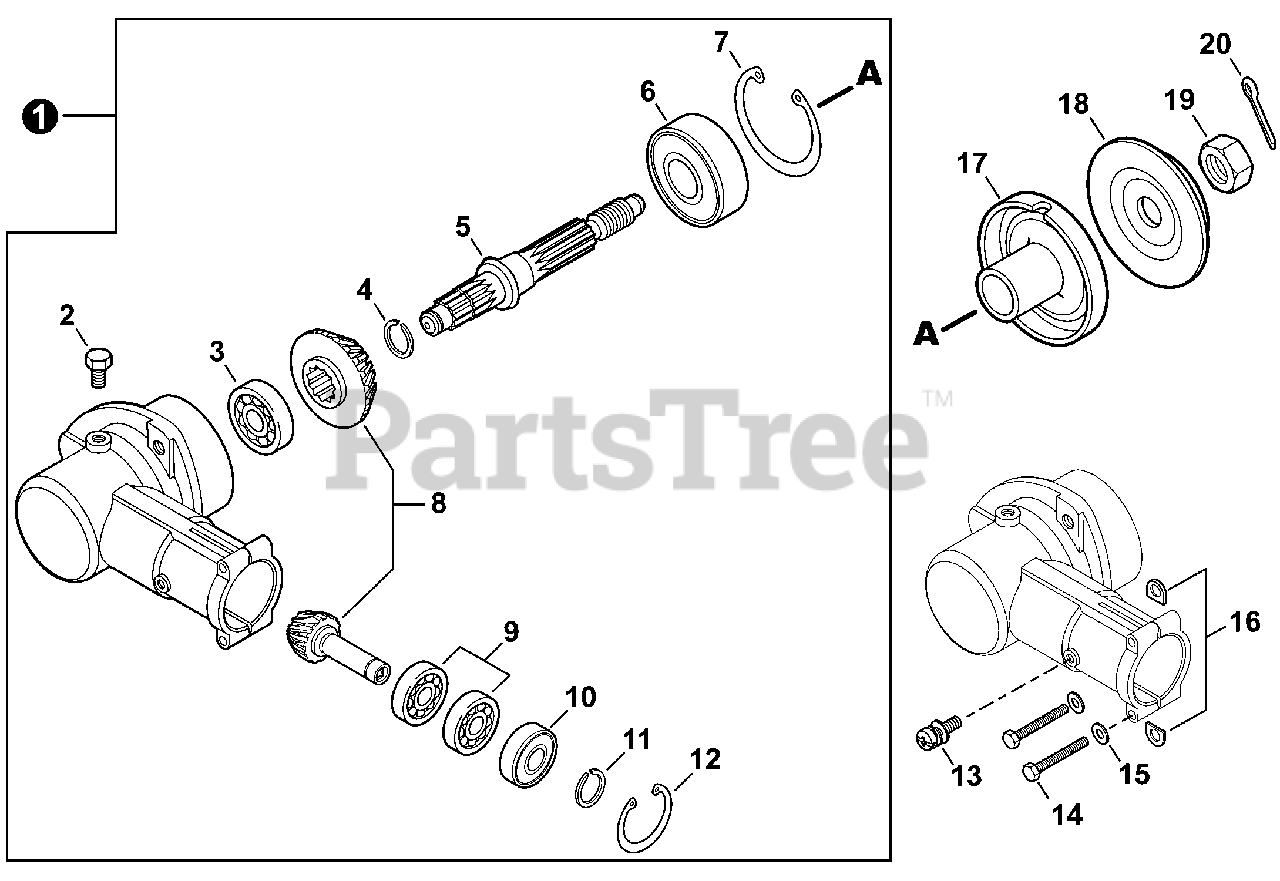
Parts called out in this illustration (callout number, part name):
1	GEAR CASE ASSY
2	BOLT M8×8
3	BEARING, BALL 629
4	RING, SNAP Ø12
5	SHAFT, GEAR
6	BEARING, BALL 6302
7	RING, SNAP Ø42
8	GEAR SET
9	BEARING, BALL 6900
10	BEARING, BALL 6900Z
11	RING, SNAP Ø10
12	RING, SNAP Ø22
13	SCREW 5×12
14	BOLT 5×30
15	WASHER, FLAT 5.5×10×0.8
16	D-WASHER
17	PLATE, ADAPTOR - UPPER
18	PLATE, ADAPTOR - LOWER
19	NUT 10×1.25 LH
20	PIN, COTTER 2×22
